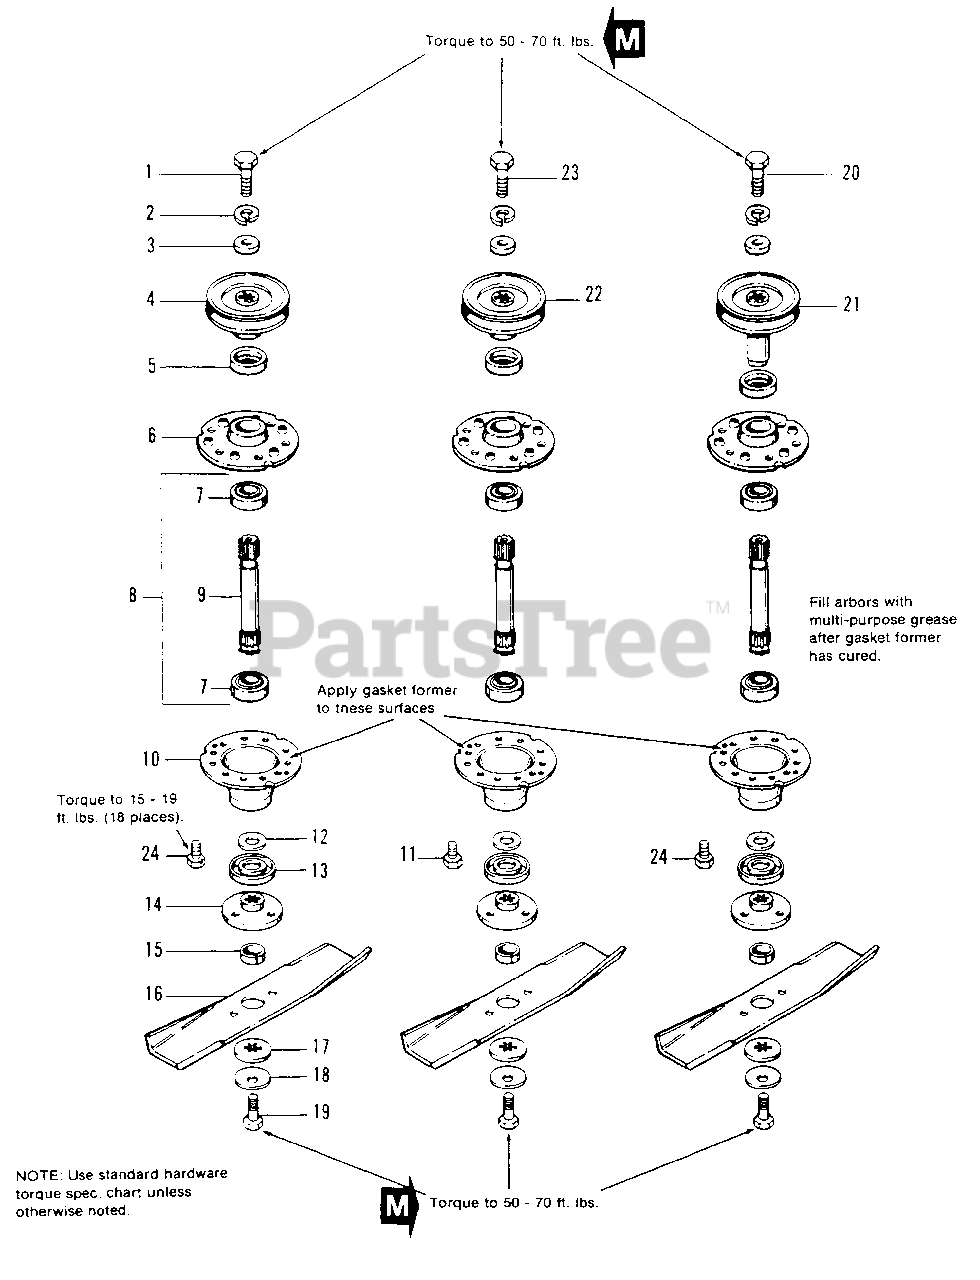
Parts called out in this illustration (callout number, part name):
1	CAPSCREW, Hex 7/16-14 x 1/2
2	LOCKWASHER, 7/16
3	WASHER, Plain, 29/64 x 1-1/4 x 1/4
4	PULLEY ASSY.
5	SHIELD, Bearing Upper, Arbor
6	HOUSING TOP
8	SHAFT & BEARING ASSY. (Incl. Ref. Nos. 7, 9 & 15)
9	SHAFT, Arbor (Incl. Ref. No. 15)
10	HOUSING, Bottom
11	SCREW, Hex, Taptite, 5/16-18 x 3/4
12	WASHER, Shim
13	SHIELD, Grass
14	ADAPTOR, Blade
16	BLADE, 42" Mower
16	BLADE, 48" Mower
17	WASHER, Spline
18	WASHER, Spring
19	CAPSCREW, Hex 7/16-14 x 1
20	CAPSCREW, Hex, 7/16-14 x 3-1/2
21	PULLEY ASSY.
22	PULLEY ASSY.
23	CAPSCREW, Hex, 7/16-14 x 1-3/4
24	SCREW, Hex Taptite, 5/16-18 x 1
